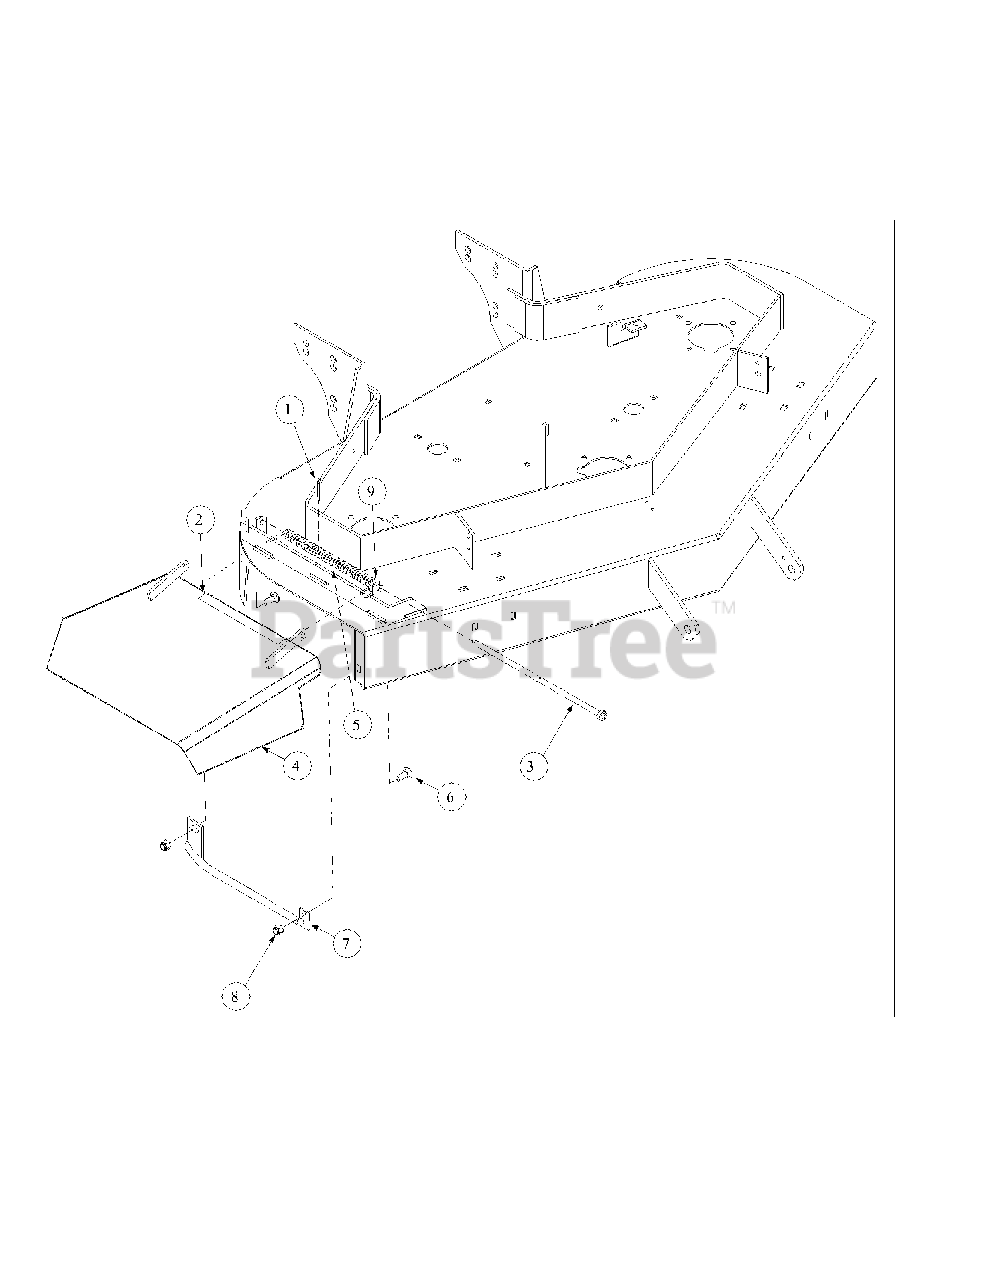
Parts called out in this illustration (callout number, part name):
1	Cotter Pin, 5/32 x 1-1/2, Zinc
2	Decal, Cut Line
3	Pin Deflector, Weldment
4	Chute 52, Weldment
5	Torsion Spring
6	Carrige Bolt, 3/8-16 x 1
7	Stiffener Assembly, 52"
8	Lock Nut, Nylon Insert, 3/8-16
9	Flat Washer, 3/8
